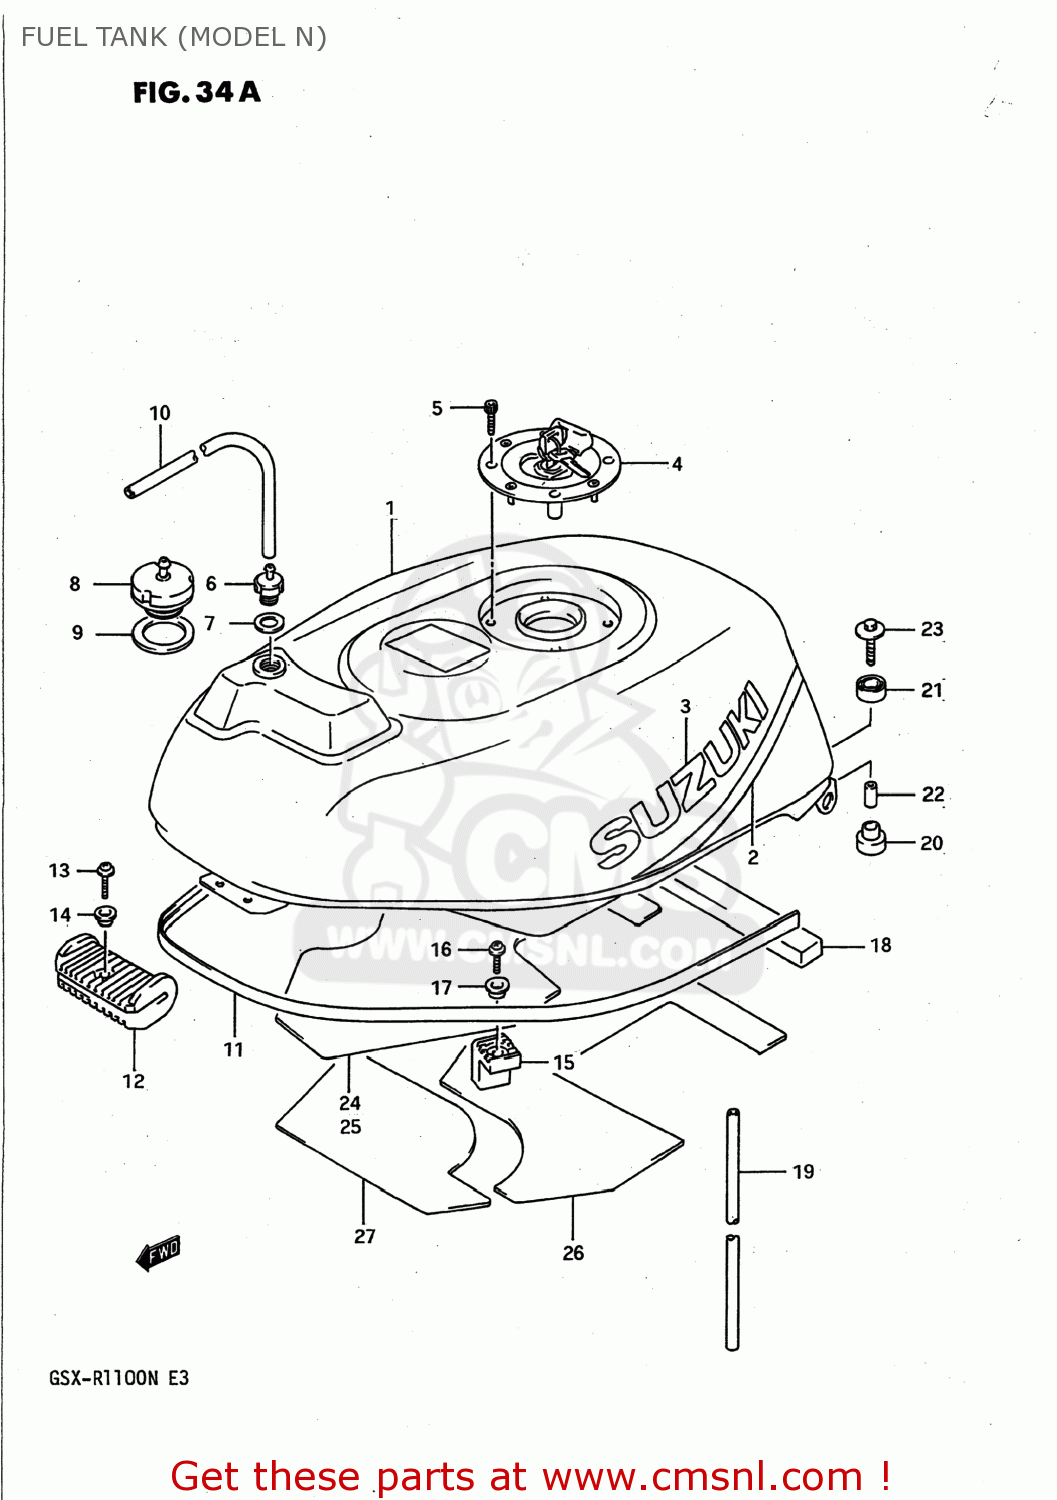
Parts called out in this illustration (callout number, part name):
1	TANK ASSEMBLY,FUEL
2	TAPE,FUEL TANK
3	EMBLEM,FUEL TANK
4	CAP SET,FUEL TANK
5	BOLT(5X20)
6	PLUG,FUEL TANK BREATHER
7	GASKET(12.5X20X2.5) (NAS)
8	(CA) VALVE,FUEL TANK BREATHER
9	GASKET 27X40X2.5 (NAS)
10	HOSE(5X8.2X600)
11	MOLDING,FUEL TANK
12	CUSHION,FUEL TANK FR
13	SCREW 5X10
14	WASHER
15	CUSHION,FUEL TANK SIDE
16	SCREW
17	WASHER
18	CUSHION, AIR SEAL
19	HOSE
20	CUSHION
21	CUSHION
22	SPACER
23	BOLT(6X35)
24	SHIELD,FUEL TANK HEAT
25	SHIELD,FUEL TANK HEAT
26	HEAT SHIELD,FUEL TANK IN
27	HEAT SHIELD,FUEL TANK IN
